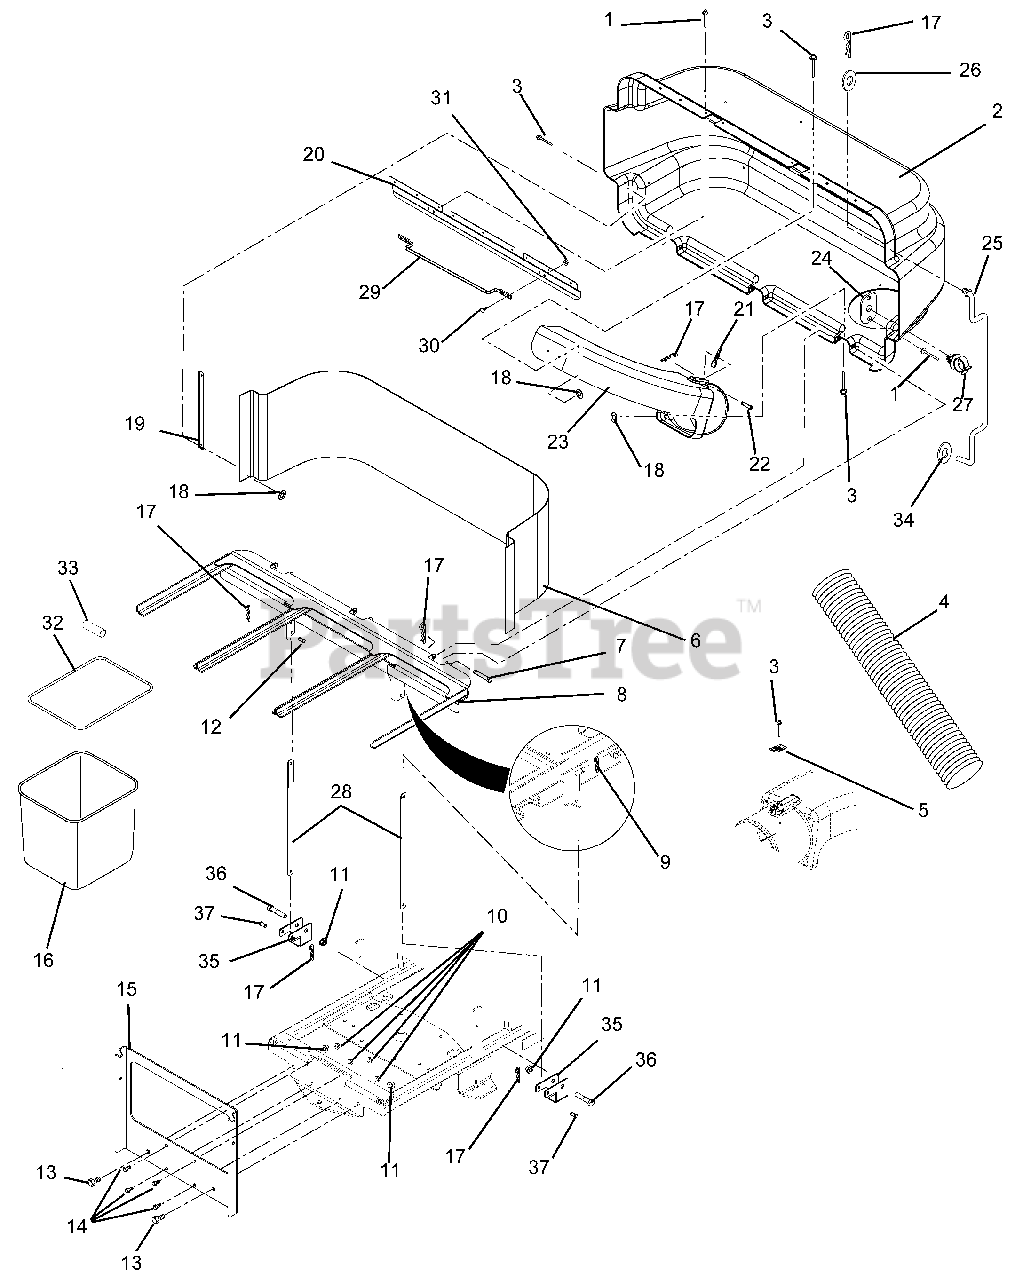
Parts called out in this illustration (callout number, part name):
1	Rivet-Pop .187 x .402
2	Cover, Bagger with Decal
3	Rivet-Pop .187 x .375
4	Hose, 7 x 38 Kanaflex 165 Clear
5	Thumb Latch
6	Screen, Bagger
7	Pin-Clevis .368/.373 x 3.25
8	Weldment, Bagger Frame
9	Pin, Hair, External- #16
10	Nut, .38-16 Nyloc Flange
11	Nut, .50-13 Nyloc Flange
12	Pin, Clevis .38 x .75
13	Bolt, Hex .50-13 x 1.00 Grade 5
14	Bolt, Hex .38-16 x 1.00 Grade 5
15	Mount, Rear Bagger
16	Bag, HVZ Mesh
17	Pin-Hair
18	Washer-Flat-Steel .219 x .50 x .049
19	Strap, Cover
20	Latch, Cover
21	Indicator, Flow
22	Pin-Clevis .31 x 2.62 Grade 5
23	Boot, Upper
24	Plate, Rod Clip
25	Prop-Rod, Bagger
26	Washer-Flat-Steel .046 x .812 x .065
27	Clip .38
28	Strap, Reinforcing
29	Bagger Handle
30	Bolt, Round Head Square Neck .25-20 x .75 Grade 5
31	Nut, Locking-Top-Flange .25-20
32	Frame, HVZ Bag
33	Hose, .38 x .50 x 3.00, Vinyl
34	Retainer, .38 Push-On
35	Clamp, HVZ Bagger Mount
36	Bolt, Hex .50-13 x 2.75 Grade 5
37	Pin, Clevis .373/.368 x 2.12
